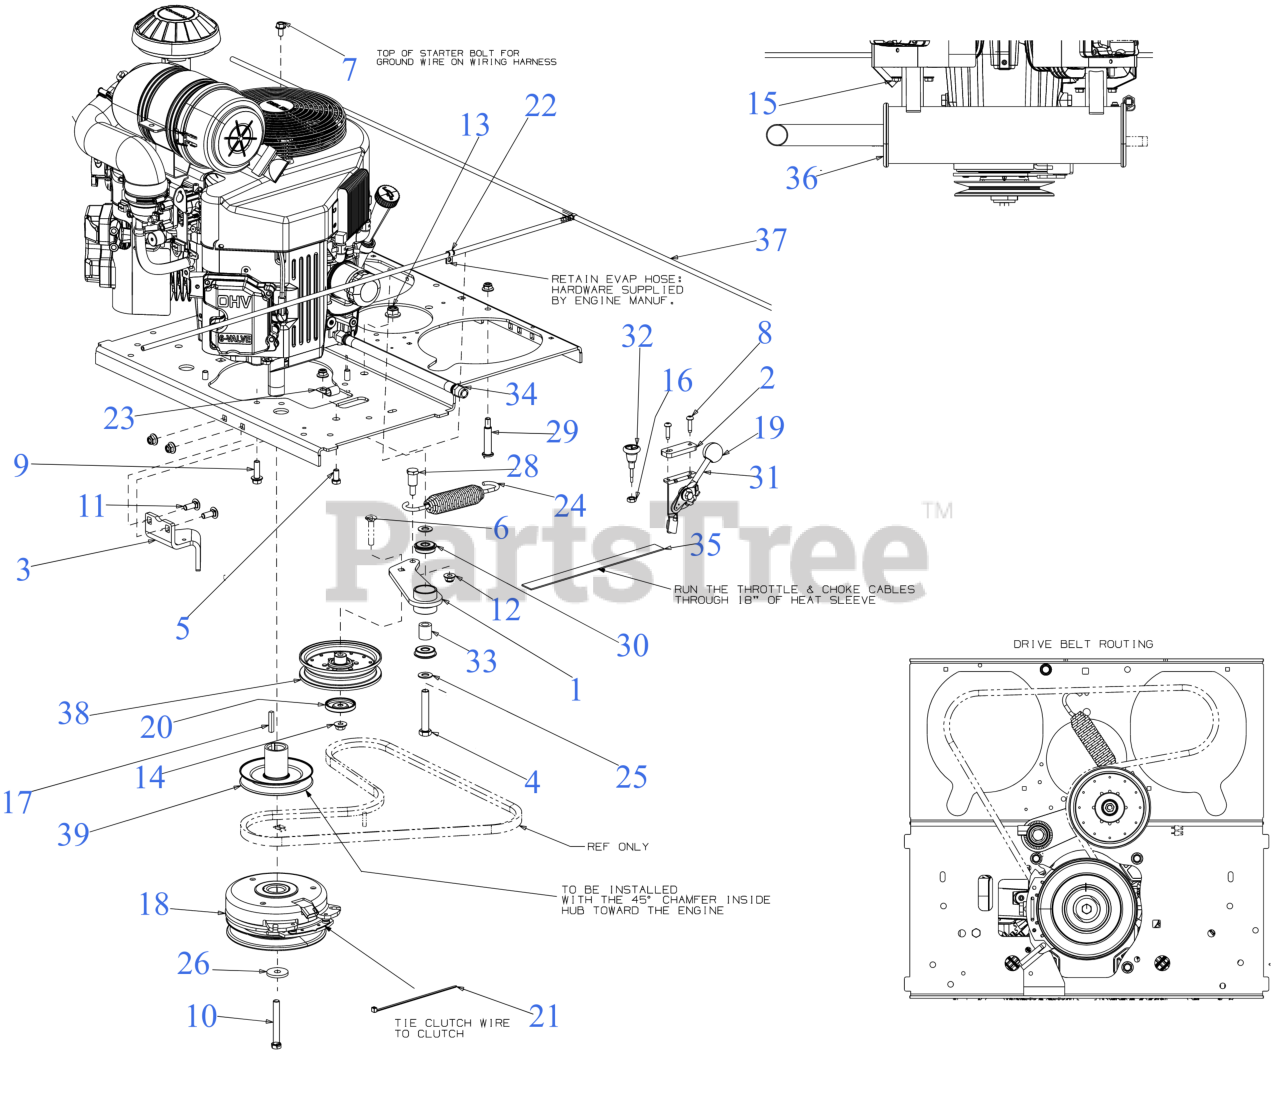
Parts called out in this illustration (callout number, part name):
1	IDLER BRACKET
3	CLUTCH RETAINER BRACKET
4	SCREW-HEX 1/2-13 x 3.00
5	HEX SCREW 3/8-16 x .75
6	CARRIAGE BOLT 3/8-16 x 2
7	SCREW M8 x 1.25 x 16MM GR8.8
8	SCREW 1/4-20 x 1.0
9	SCREW 3/8-16 x 1.25 GR5
10	SCREW 7/16-20 x 3.25 GR5
11	CARRIAGE BOLT 3/8-16 x 1.00 GR5
14	FLANGE LOCK NUT
15	HEX FLANGE NUT
16	HEX JAM NUT 3/8X24
17	SQUARE KEY 1/4 x 1.50
18	ELECTRIC PTO CLUTCH
20	PULLEY CAP
21	7" CABLE TIE
22	MOUNTING CLAMP
23	J TYPE CLIP
24	EXTENSION SPRING W/HOOK
25	FLAT WASHER .510 x .995
26	FLAT WASHER .45 x 1.5 x .172 HT
28	SHOULDER SCREW .625 x .875 x 3/18
29	SHOULDER BOLT (.50 X 2.0 x 3/8 -16)
30	ROLLER BEARING .5X1.37X.44
31	THROTTLE CABLE 59"
32	CHOKE CABLE
33	SPACER 0.51 x 0.88 x 1.00
34	OIL DRAIN HOSE
35	HEAT SHIELD 24"
36	MUFFLER - KAWASAKI 1000
38	FLAT IDLER PULLEY
39	ENGINE PULLEY
